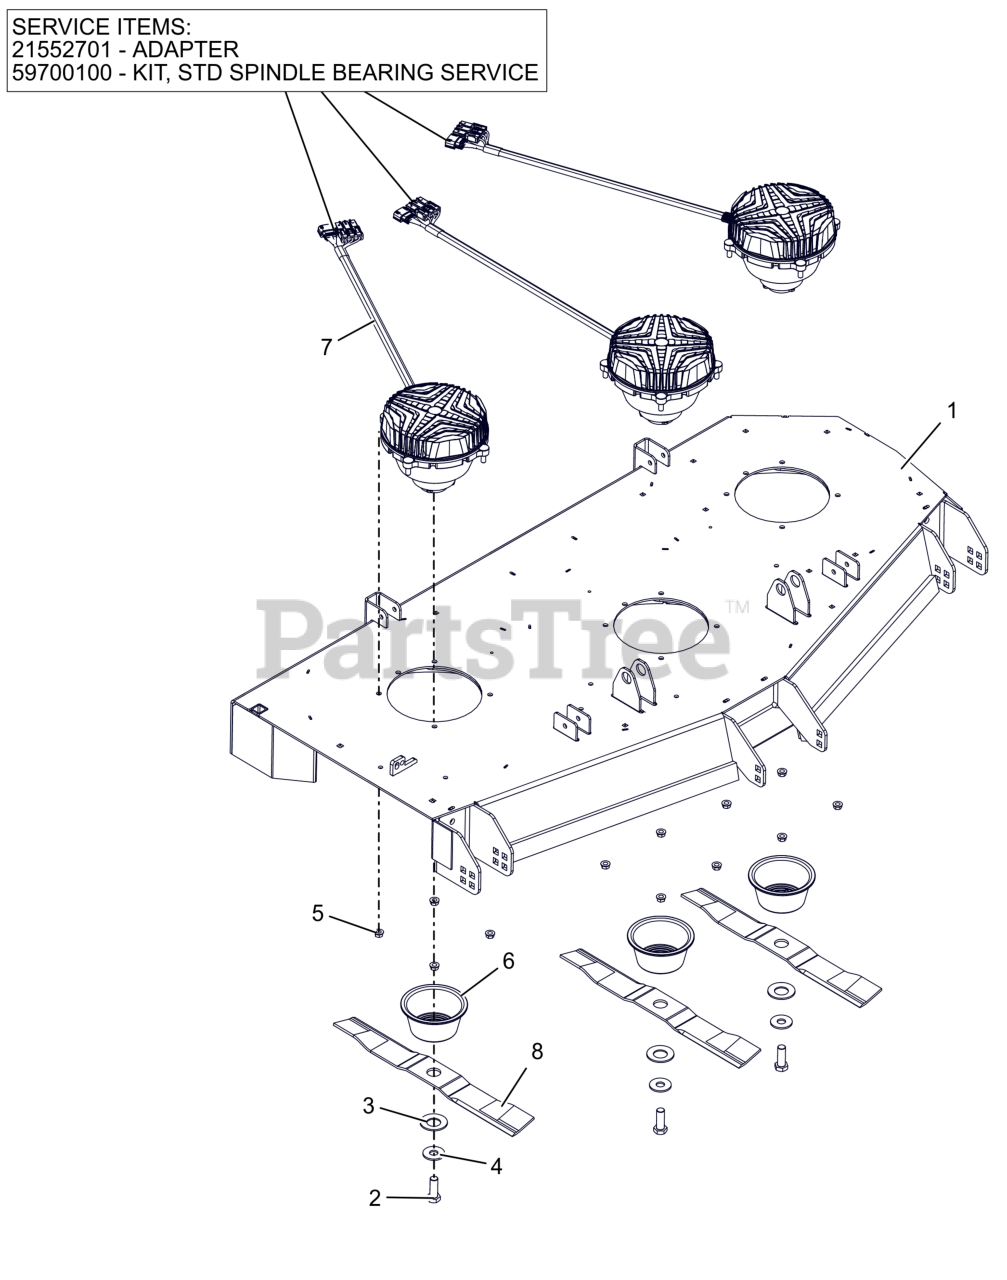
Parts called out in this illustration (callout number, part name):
1	WLDMT, 60" PSEV SIDE DISCH DECK (ORANGE)
2	BLT, HEX .62-18X1.75 G8 ZCC
3	WSHR, BLVL - .56X28.5X3 PHOS.COAT
4	WSHR, HRDN 0.687X1.75X0.134 HRD
5	NUT-LK-CTR-FLG .375-16 GF ZCC
6	GUARD, SPINDLE LOWER
7	MOTOR, SPINDLE-CW
8	BLADE, MOWER 20.5"
8	ADAPTER
8	KIT,STD SPINDLE BEARING SERVICE
